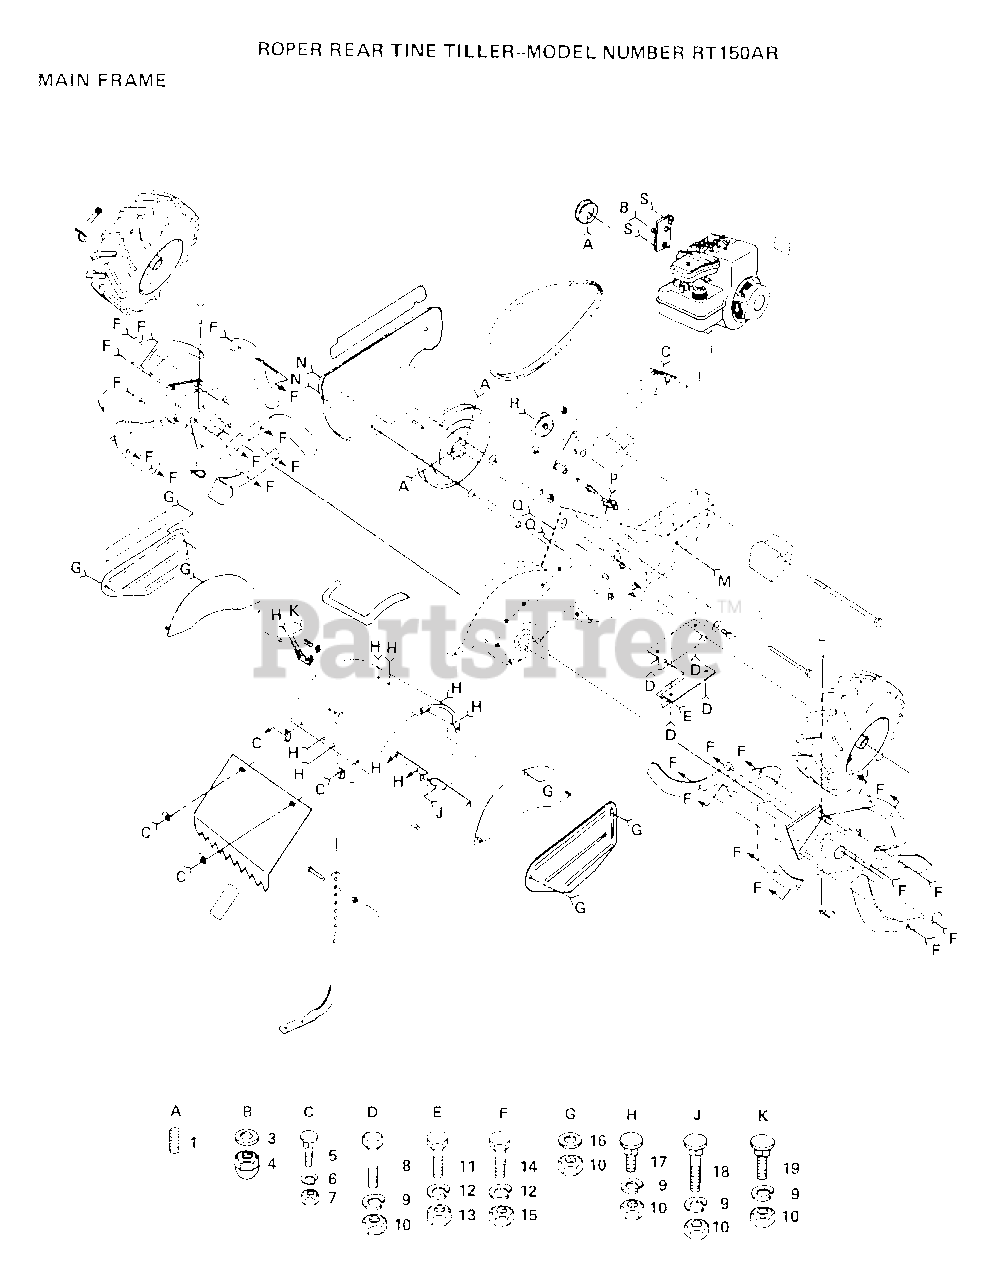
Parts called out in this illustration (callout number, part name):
1	SET SCREW
3	WASHER
4	NUT TI
5	BOLT
6	LOCKWASHER
8	BOLT.HEX.5/16-1.5
9	LOCKWASHER
10	NUT.HEX.5/16-18
11	BOLT
12	LOCKWASHER
13	NUT.HEX.3/8-16UNC
14	BOLT
16	WASHER
17	BOLT
18	BOLT CRT
19	BOLT
